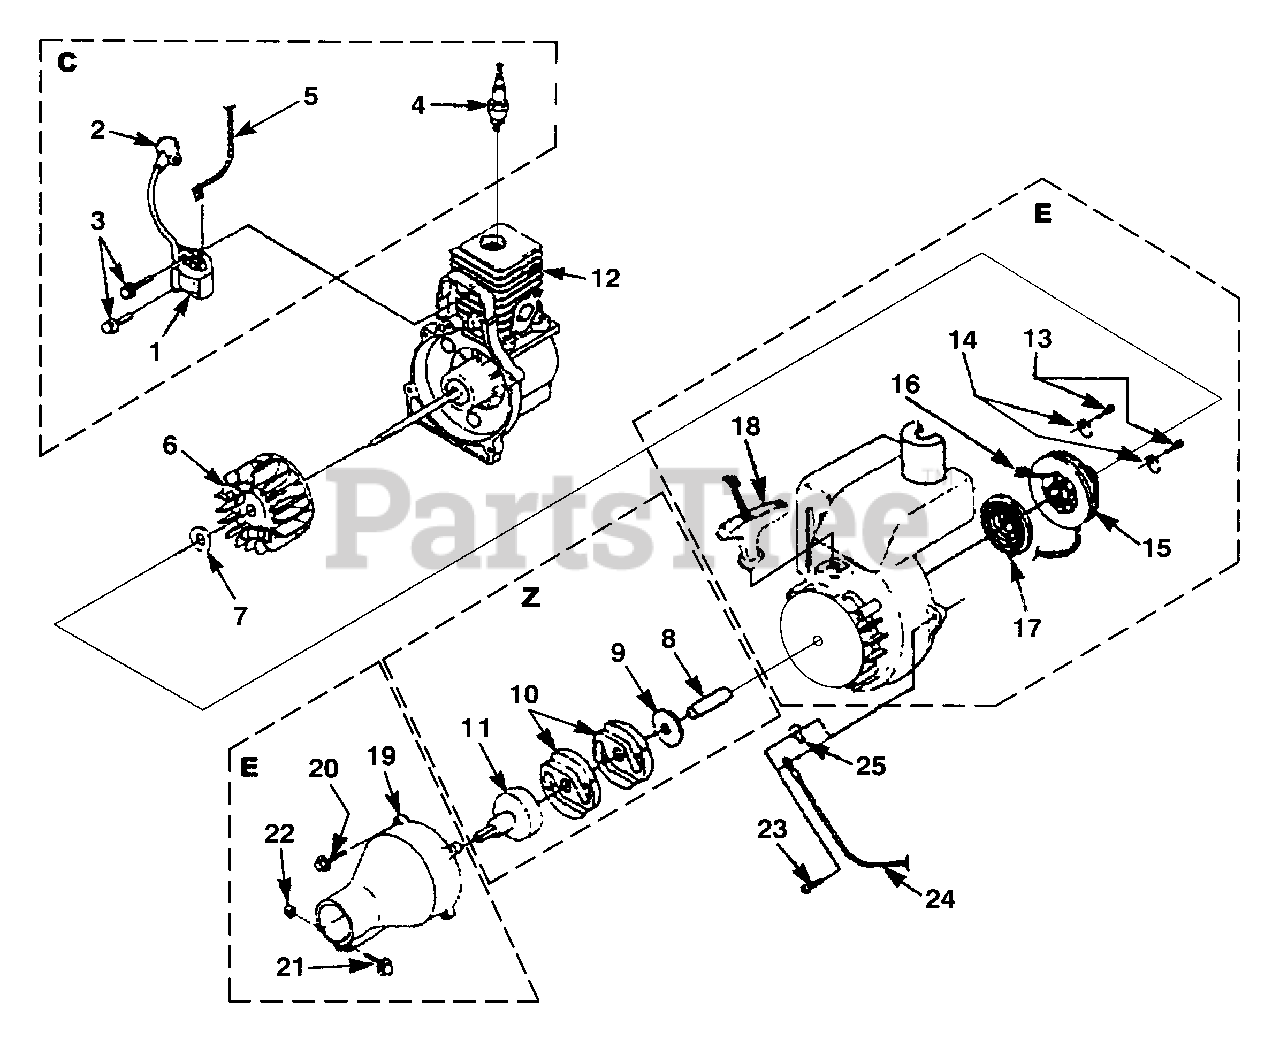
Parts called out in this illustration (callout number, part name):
1	MODULE - Ignition
2	TERMINAL & COVER
3	SCREW - Taptite (8-32 X 1")
4	SPARK PLUG
5	LEAD - Electrical
6	ROTOR KIT
7	WASHER - Flat
8	SPACER
9	WASHER - Flat
10	CONNECTOR - Drive
10	CLUTCH
11	CONNECTOR & DRUM
12	SHORT BLOCK
13	SCREW - Plastite (#10-1/2")
14	BRACKET - Retaining
15	PULLEY - Starter
16	ROPE - Starter (42")
17	SPRING & CONTAINER
18	GRIP - Starter
19	TUBE ADAPTER
20	SCREW - Hex Hd (10-24 X 7/8")
21	SCREW - Sems Hex Hd (10-24 X 1-1/8")
22	NUT (10-24)
23	SCREW - Taptite (10-24 X 3/4")
24	LEAD - Ground
25	TERMINAL - Male
C	IGNITION KIT
Z	CLUTCH AND DRUM KIT
E	COMPLETE STARTER ASSEMBLY
